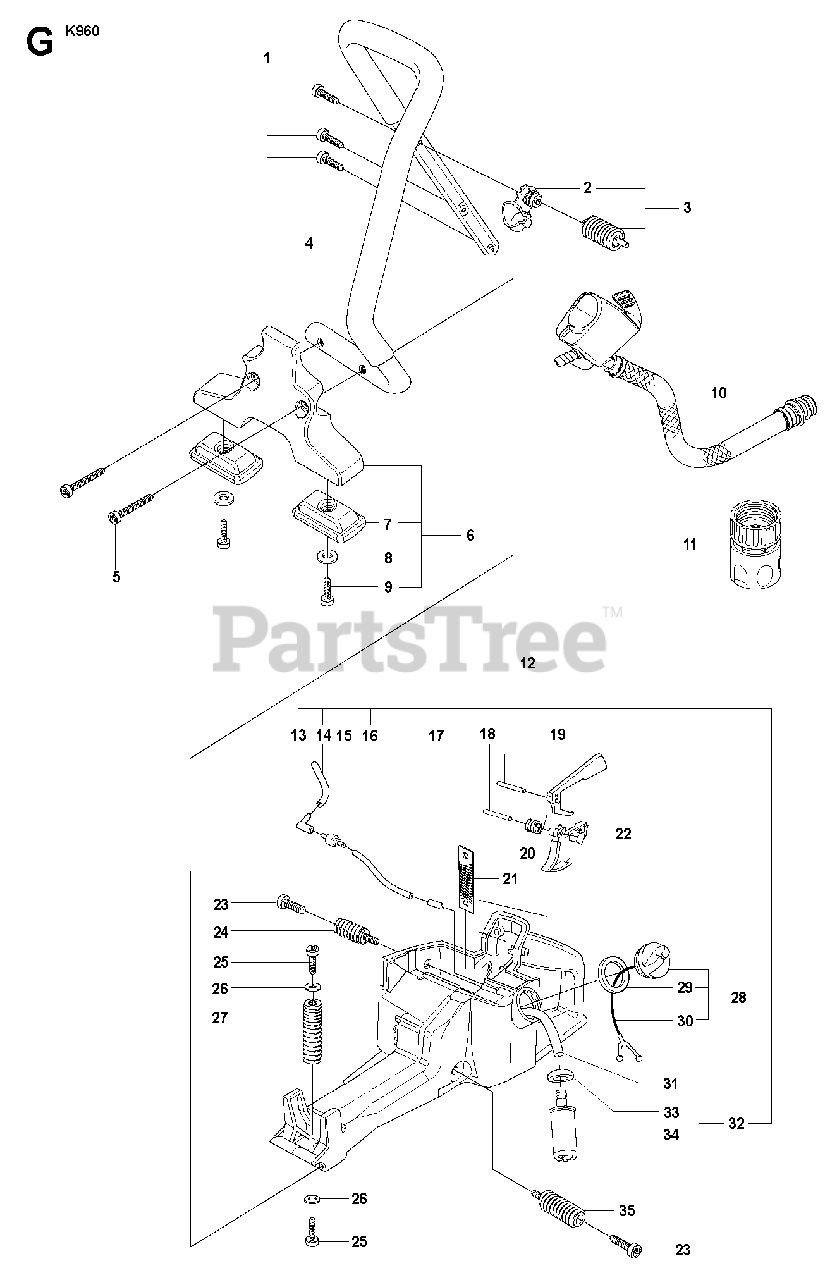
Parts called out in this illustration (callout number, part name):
1	SCREW ITXSCT
3	ANTIVIBRATION ELEMENTIncl. 2
5	SCREW ITXSCT
9	SCREW ITXSCM
10	HOSE ASSY
11	COUPLER
12	FUEL TANKIncl. 13 - 19, 28, 32
13	CONNECTION BEND
14	FUEL HOSE
16	FUEL HOSE
18	PARALLEL PIN
19	THROTTLE LOCKOUT
20	SPRING THROTTLE TRIG
23	SCREW ITXSCM
24	ANTIVIBRATION ELEMENT
25	SCREW ITXSCM
27	ANTIVIBRATION ELEMENT
28	TANK CAP ASSYIncl. 29, 30
31	FUEL HOSE
32	FUEL FILTERIncl. 33, 34
